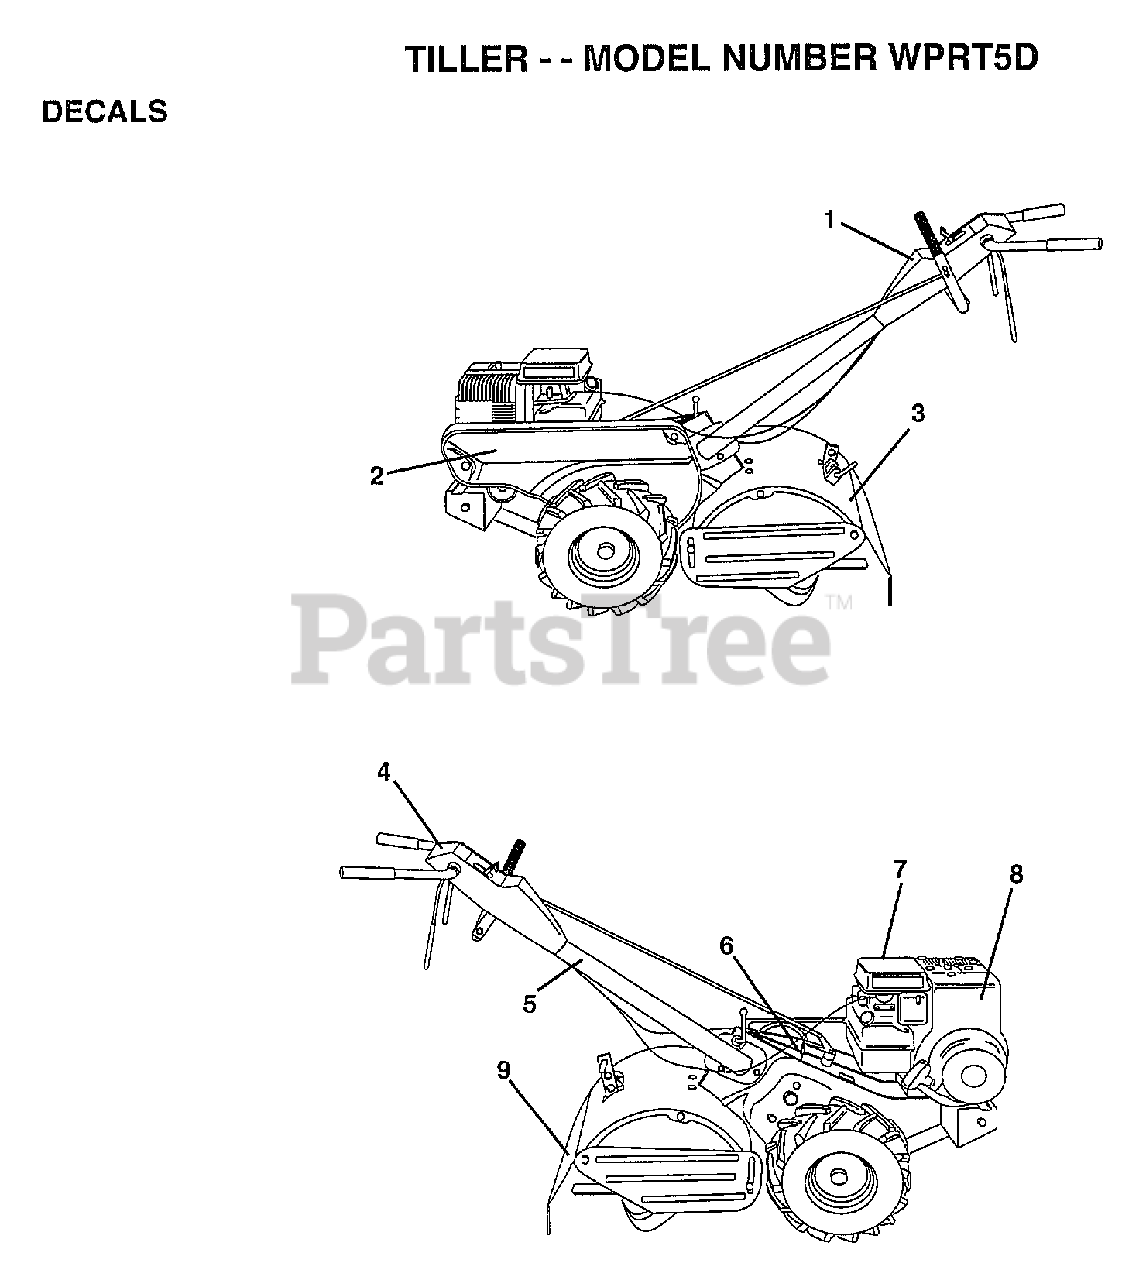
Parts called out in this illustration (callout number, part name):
1	DECAL.PNL.CONTROL
2	DECAL.GD.BELT.5HP
3	DECAL.SHLD.TINE
4	DECAL.INSTRUCTION
5	DECAL TI
6	DECAL CRT
8	DECAL, BRIGGS & STRATTON
9	DECAL TI
